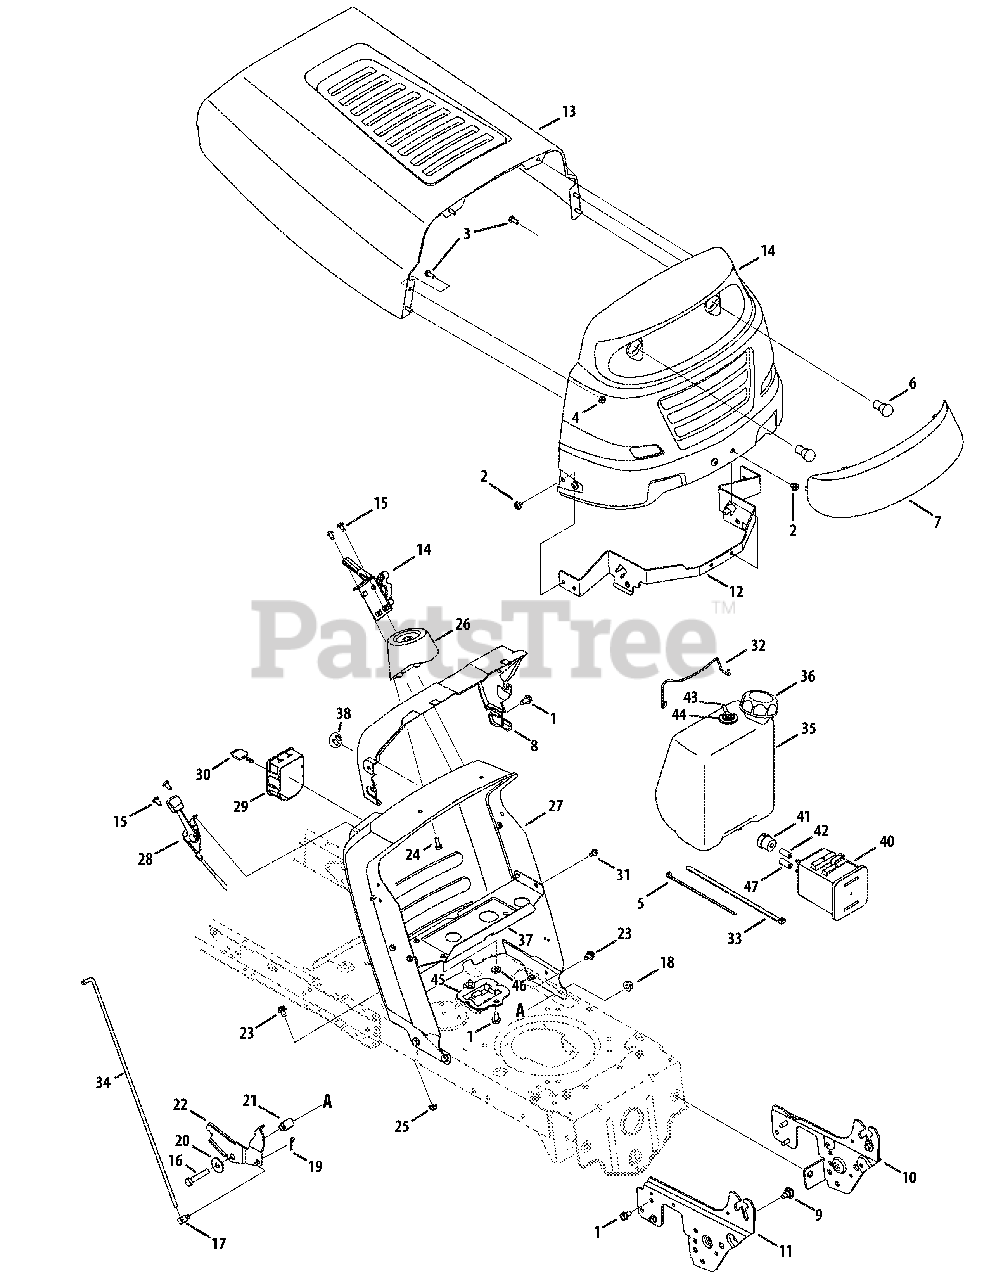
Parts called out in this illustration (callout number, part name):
1	Screw, 5/16-18 x .750
2	Screw, 5/16-18 x .375
3	Hex Screw, 1/4-20 x .620
4	Nut, Hex Flange Insert Lock, 1/4-20
5	Cable Tie, 3/16 x .05 x 7.4
7	Grill Lens, 1 Style
8	Dash Collar
9	Shoulder Screw, 5/16-18
10	Left Support Pivot Bracket
11	Right Support Pivot Bracket
12	Hood Pivot Bracket
13	Hood Assembly, 1 Style
14	Speed Selector, 7-Speed
15	Self-Tap Screw, 1/4-20
16	Hex Head Screw, 3/8-16
17	Ferrule, 1/4-20 x 1.00
18	Nut, Hex Flange Insert Lock, 3/8-16
19	Hair Pin Clip
20	Flat Washer, .411 x 1.25 x .100
21	Flange Spacer
22	Speed latch
23	Self-Tap Screw, 5/16-18
24	Hex Screw, 1/4-15
25	Nut, Hex Flange Ins. Lock, 5/16-18
26	Steering Support
28	Throttle/Choke Assembly
29	Key Switch Module
31	Screw, Hd. Tapp, 1/4-20 x .5
32	Assembly Rod
33	Cable Tie
34	Speed Selector Control Rod
35	1.36 Gallon CARB Fuel Tank
36	Fuel Cap
37	Gas Tank Support Bracket
38	Choke Plug
40	Carbon Cannister
41	Filter Vent
42	Low Perm Fuel Line 3/16 White
43	Rollover Valve
44	Rubber Grommet
45	Cannister Bracket
46	Flat Washer, .344 x.750 x .120
47	Low Perm Fuel Line 7/32 Yellow
